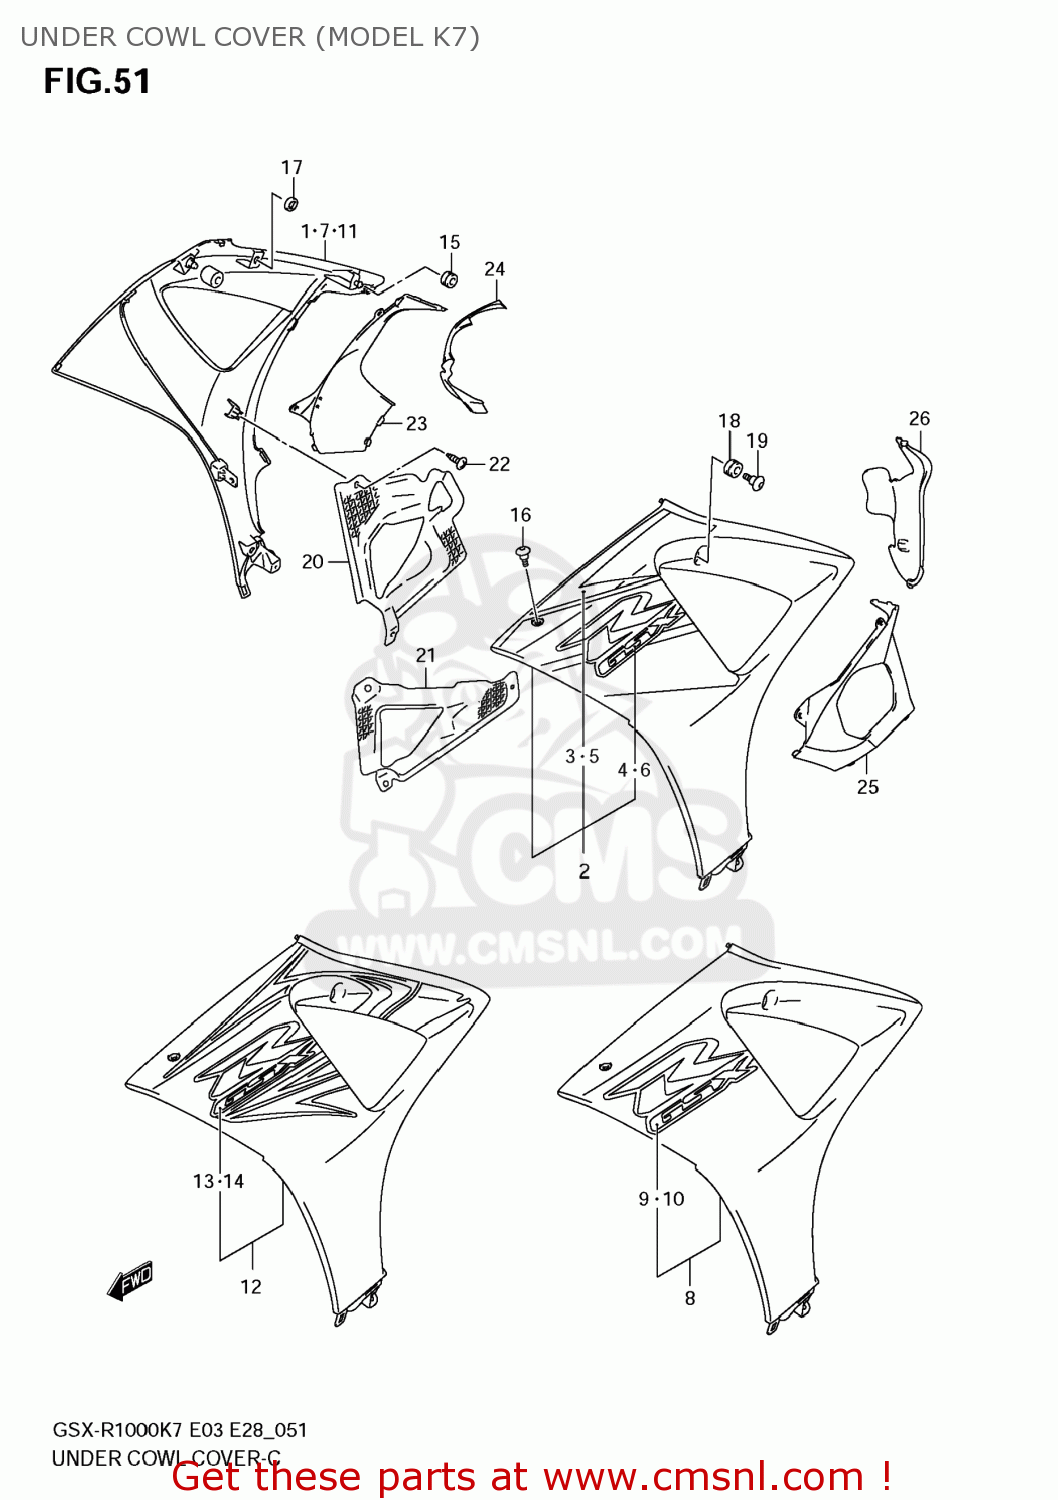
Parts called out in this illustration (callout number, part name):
1	COVER,UNDER COWL,R(BLUE)
2	COVER,UNDER COWL,L(BLUE)
3	TAPE,COVER UNDER COWL,R
4	TAPE,COVER UNDER COWL SIDE,R
5	TAPE,COVER UNDER COWL,L
6	TAPE,COVER UNDER COWL SIDE,L
7	COVER,UNDER COWL,R(BLACK)
8	COVER,UNDER COWL,L(BLACK)
9	EMBLEM,GSXR,R
10	EMBLEM,GSXR,L
11	COVER,UNDER COWL,R(BLACK)
12	COVER,UNDER COWL,L(BLACK)
13	TAPE SET,COVER UNDER COWL,R
14	TAPE SET,COVER UNDER COWL,L
15	CUSHION
16	SCREW(5X13)
17	CUSHION
18	SCREW(6X20)
19	CUSHION
20	SHIELD,UNDER COWL HEAT,R
21	SHIELD,UNDER COWL HEAT,L
22	SCREW
23	COVER,UNDER COWL LWR,R
24	PROTECTOR,COWLING UNDER
25	COVER,UNDER COWL LWR,L
26	PROTECTOR,COWLING UNDER
